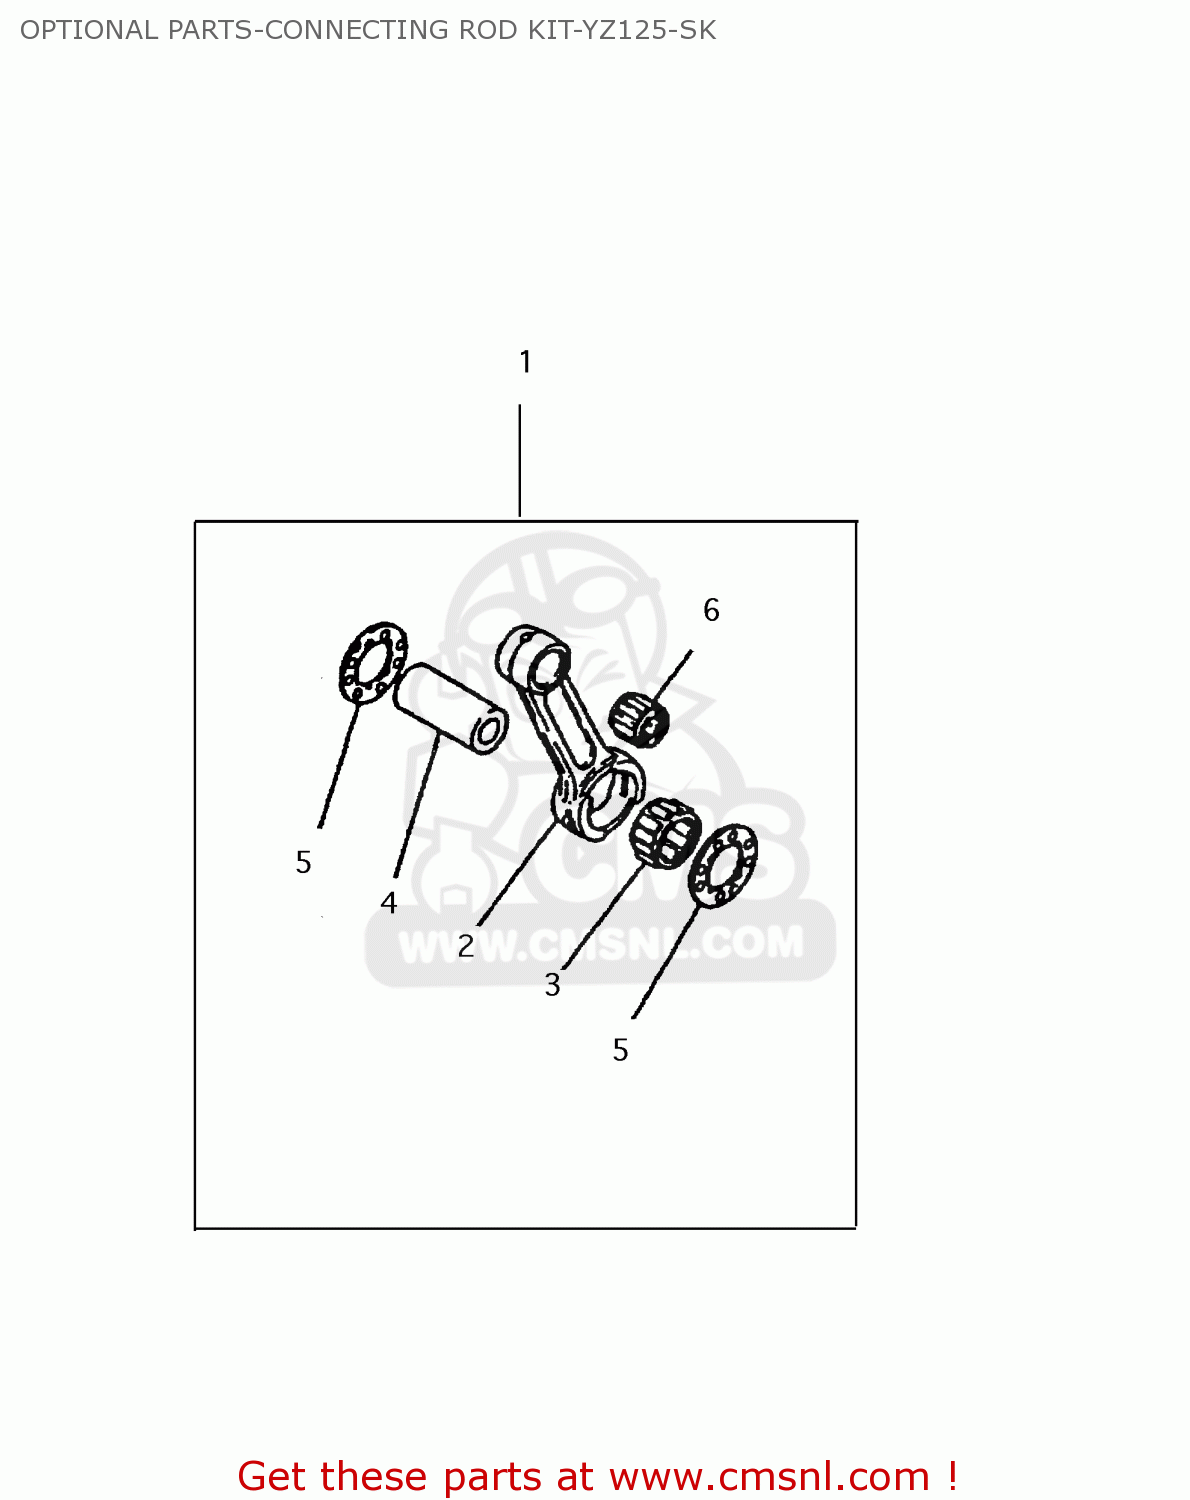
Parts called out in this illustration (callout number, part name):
1	CONNECTING ROD ASSY
2	ROD, CONNECTING
3	BEARING, CYLINDRICAL(4PE)
4	PIN, CRANK 1
5	WASHER (164-11685-00)
6	BEARING, CYLINDRICAL(4XM)
